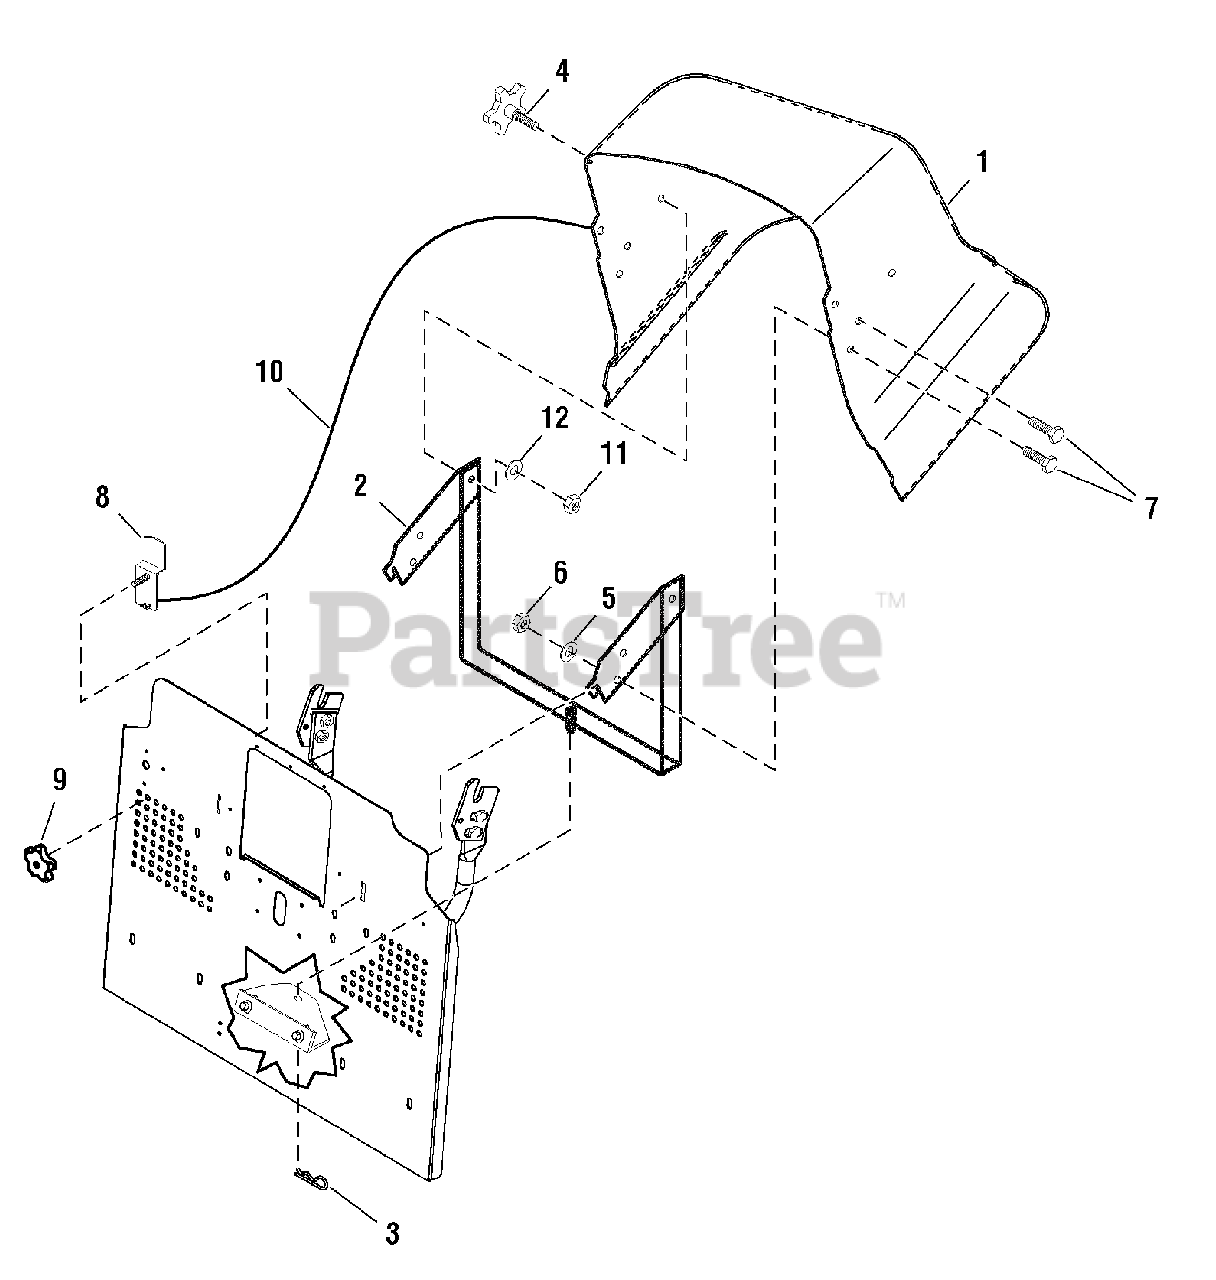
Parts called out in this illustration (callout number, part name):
1	DEFLECTOR
2	DEFLECTOR HOLDER
3	HAIR PIN
4	SCREW, With Starlike Knob
5	WASHER, 6.4
6	NUT, Selflock, M6
7	SCREW, Flat Head, M6x16
9	NUT, With Starlike Knob
10	CORD, Hair Line, 550mm
11	NUT, M8
12	WASHER, 8.4
